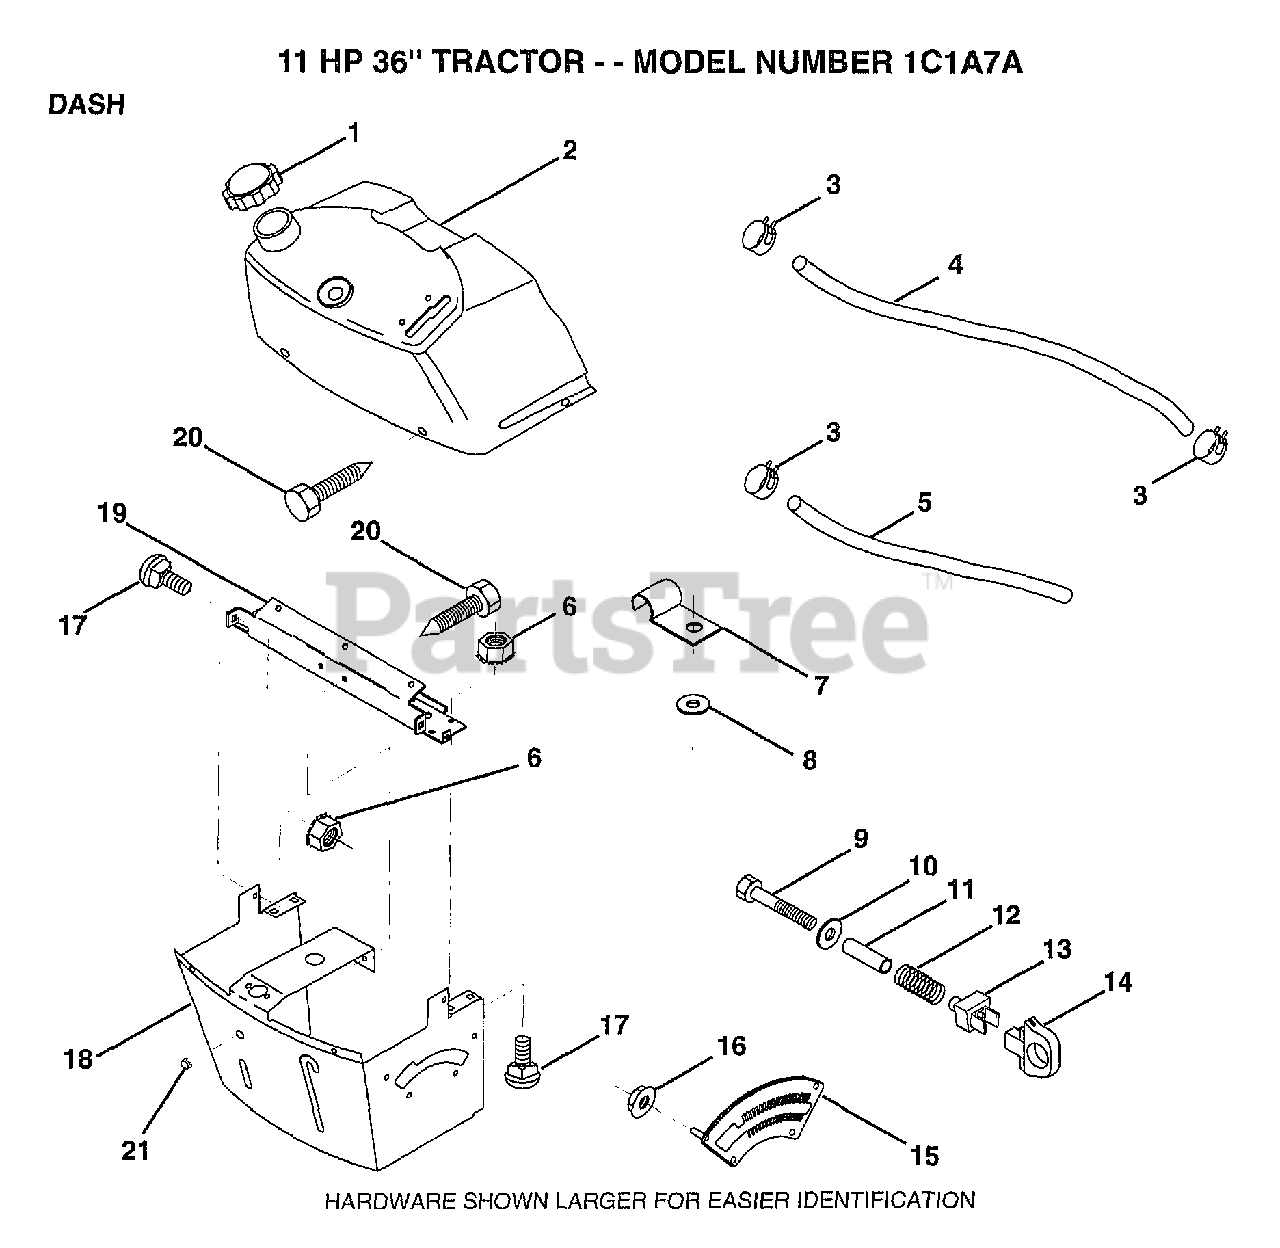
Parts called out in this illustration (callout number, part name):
1	CAP BLK FUEL LR
2	TANK.ASM.DASH.LR
3	HOSE CLAMP
5	FUEL LINE T
6	NUT
7	CLIP T
8	WASHER PM
9	BOLT
11	SPACER SPLIT
12	SPRING M
13	"KNOB,HGT RETAINER"
14	KNOB
15	ADJUSTER QUAD
16	NUT
17	BOLT
18	SUPT ASSY DASH
19	CROSS BRACE
20	SCREW.1/4-20X1/2
21	PLUG DOME
